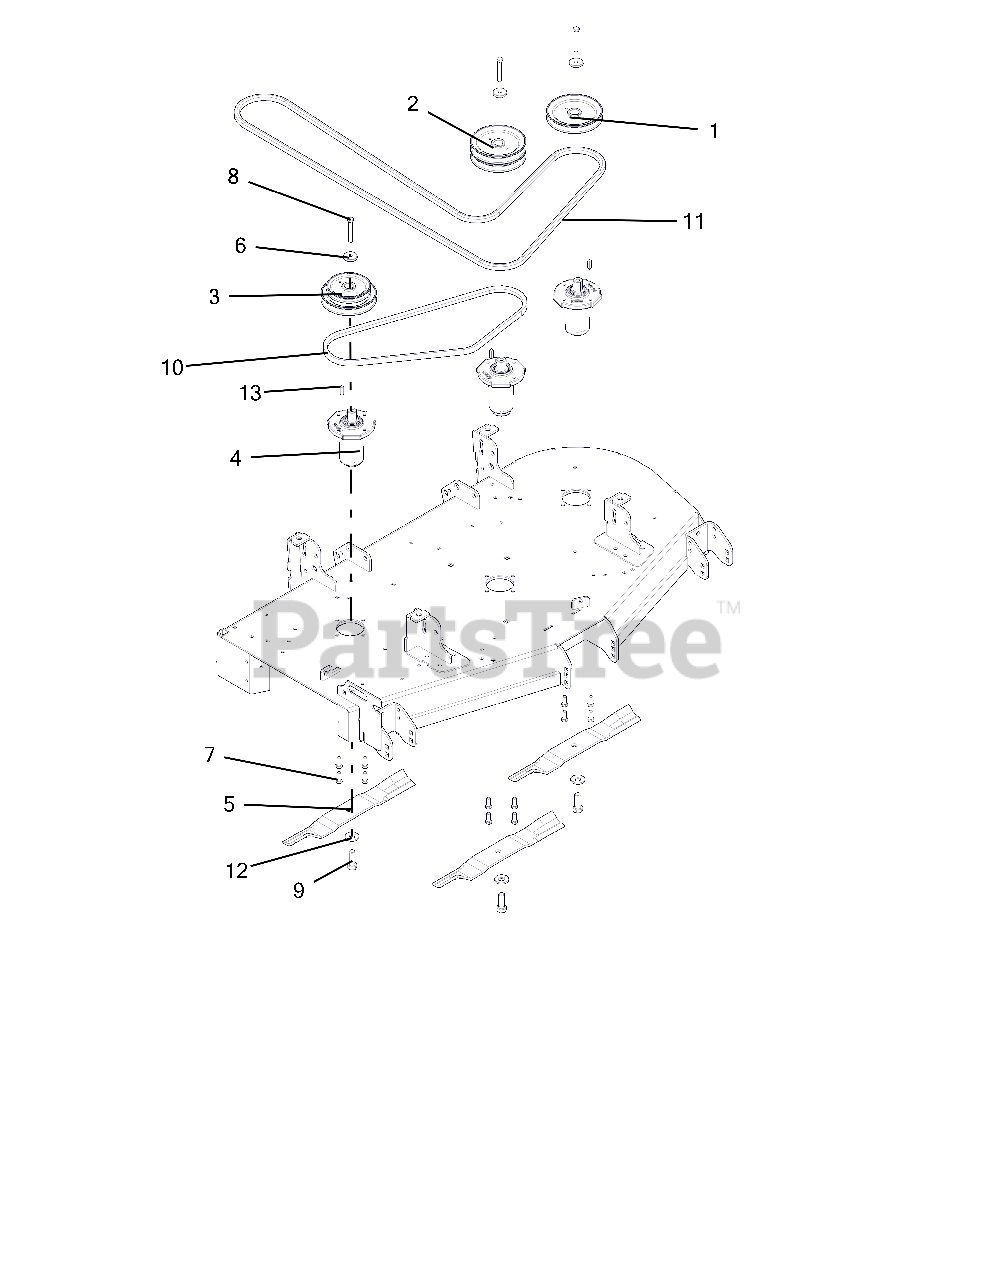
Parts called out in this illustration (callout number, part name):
1	PULLEY, SINGLE -1" ID X 6.00" OD-BLACK
2	PULLEY, DOUBLE -1" ID X 6.00" OD-BLACK
3	PULLEY, DOUBLE -1" ID X 6.00" & 4.75" OD
4	SERVICE, ASM SPINDLE- DUCTILE
5	BLADE, 18.00" MOVER
6	RETAINER, SHEAVE SPINDLE
7	BLT-HEX .38-16X1.00 GR5 YWZC EP30
8	BLT-HEX .38-16X2.75 GR8 YWZC
9	BLT, HEX .62-18X1.75 GR8 YWZC
10	BELT, B 56.00 RAW COGGED
11	BELT, BB 118.00 WRAPPED HEX
12	WSHR, BLVL .63X1.625X.14
13	KEY-SQ .250X.250X1.00 RC 40-50
